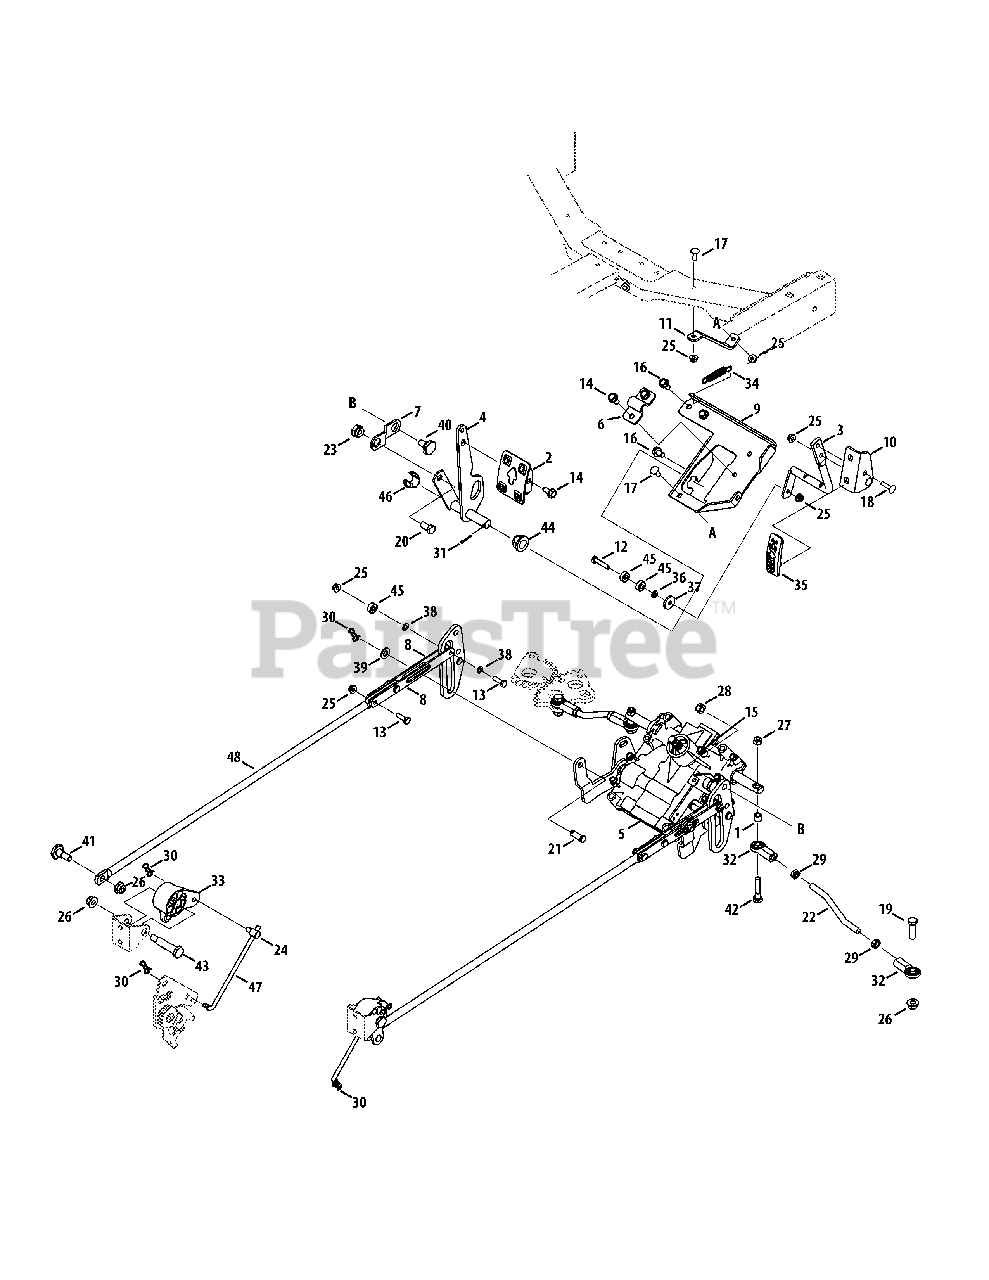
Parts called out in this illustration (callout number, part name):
1	Spacer, 344 x .500 x .375
2	Forward Pedal Assembly
3	Reverse Pedal Rod
4	Forward Bracket Assembly
5	Steering Assembly
6	Reverse Bearing Bracket
7	Control Bracket
8	Steering Link Plate
9	Pedal Mount Bracket
10	Reverse Pedal Bracket
11	Pedal Mount Plate Support Bracket
12	Hex Head Screw, 1/4-20 x 1.25
13	Hex Screw, 1/4-20 x .875
14	Hex Washer Screw, 5/16-18 x .750
15	Hex Washer Screw, 1/4-20 x .500
16	Hex Washer Screw, 5/16-18 x .625
17	Carriage Screw, 1/4-20 x .75
18	Carriage Screw, 1/4-20 x 1.00
19	Hex Screw, 3/8-16 x 1.25
20	Hex Screw, 3/8-16 x .750
21	Clevis Pin, .375 x .969
22	Rod, 3/8 x 5.0
23	Neutral Adjustment Hub
24	Adjustment Ferrule, 1/4-28 x 1.000
25	Flange Lock Nut, 1/4-20
26	Flange Lock Nut, 3/8-16
27	Hex Lock Nut, 5/16-24
28	Hex Lock Nut, 3/8-16
29	Jam Nut, 3/8-24
30	Bow-Tie Cotter Pin, 72
31	Cotter Pin, 3/32 x .750
32	Femaile Ball-Joint
33	Pivot Arm, LH
34	Extension Spring, .429 x 2.515
35	Reverse Foot Pad
36	Flat Washer, .281 x .500 x .063
37	Flat Washer, .265 x .938 x .120
38	Flat Washer, .281 x .50 x .04
39	Thrust Washer, .375 x .812 x .060
40	Shoulder Screw, .625 x .217
41	Shoulder Screw, .500 x .434
42	Shoulder Screw, 375 x .48
43	Shoulder Screw, .500 x 1.825
44	Hex Flange Bearing
45	Ball Bearing, .25 x .6875 x .25
46	Hex Flange Bearing, .628
47	Hydro Control Rod
48	Hydro Link Rod
